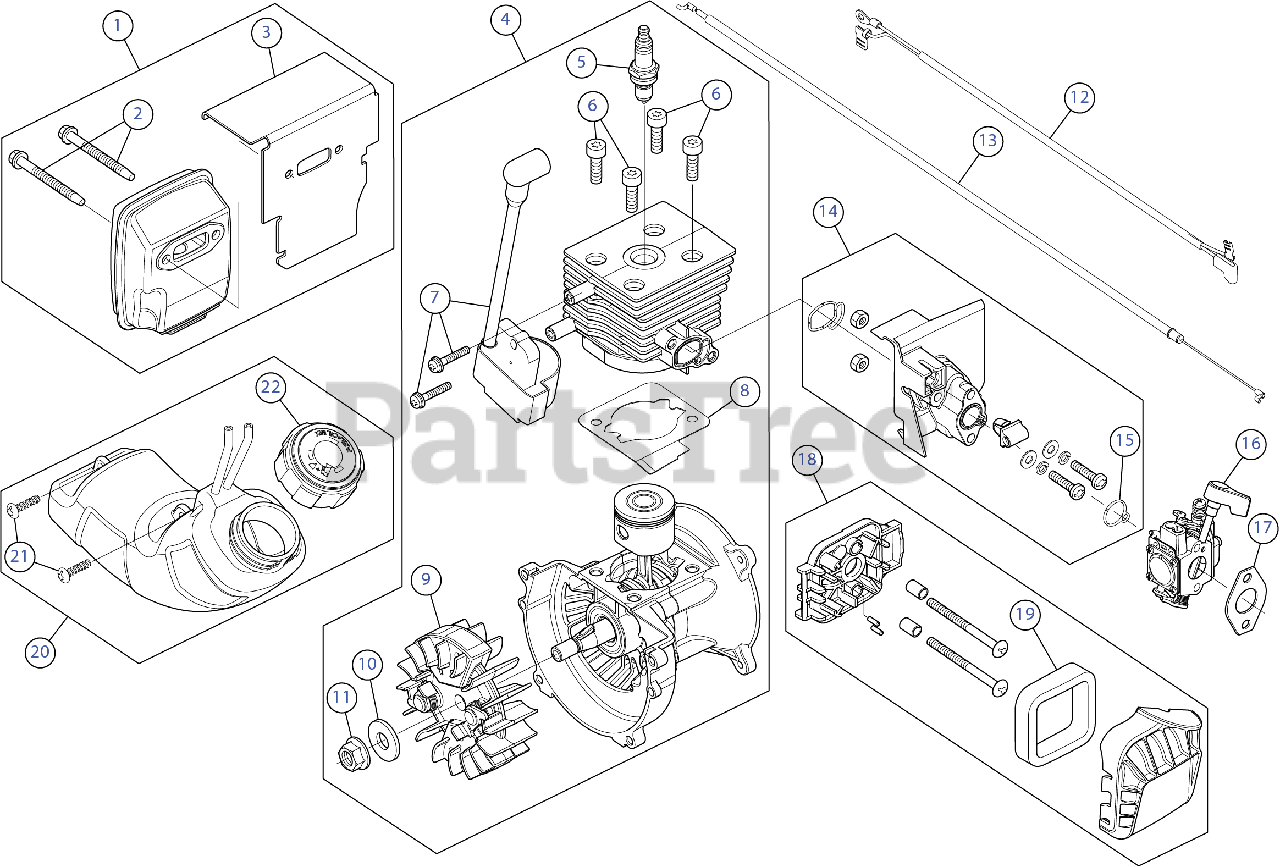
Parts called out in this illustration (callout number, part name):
1	MUFFLER ASSEMBLY 27CC
2	MUFFLER SCREW
3	MUFFLER GASKET
4	SHORT BLOCK
5	SPARK PLUG
6	SCREW 1/4 x 20 x .8125
7	MODULE ASSEMBLY
8	GASKET CYL
9	FLYWHEEL ASSEMBLY
10	WASHER .406X1.0X.095
11	NUT 3/8-24
13	THROTTLE CABLE
14	INTAKE ASSEMBLY
16	CARBURETOR ASSEMBLY
17	GASKET CARB
18	AIRCLEANER ASSEMBLY
20	FUEL TANK ASSEMBLY
21	SCREW 8-16 x 3/4
22	ASSEMBLY, FUEL CAP (RED TOP)
